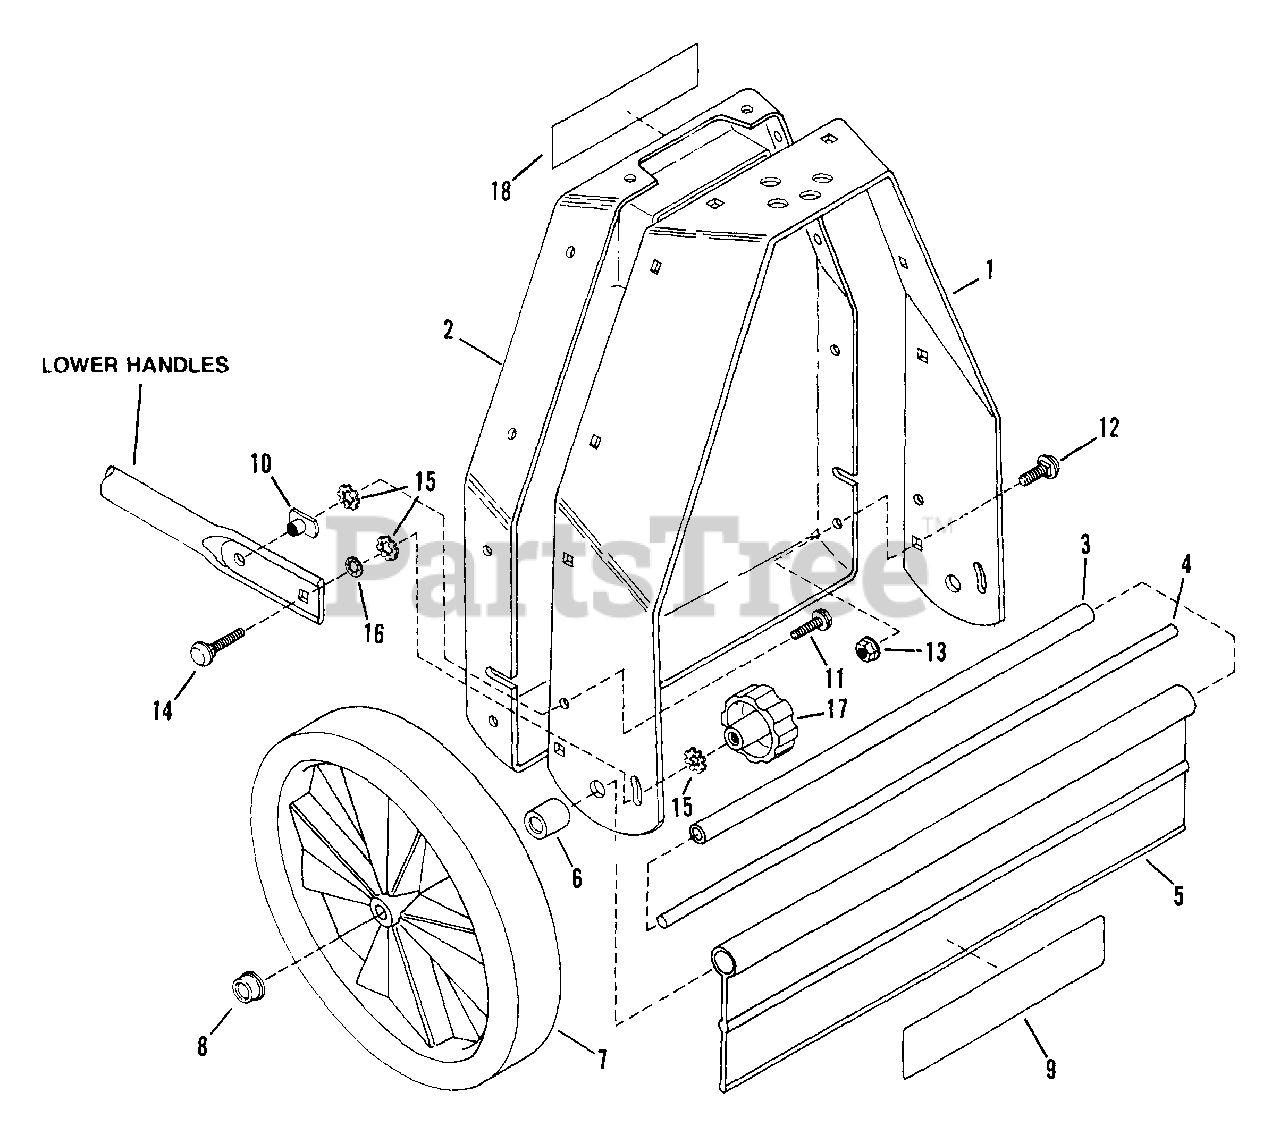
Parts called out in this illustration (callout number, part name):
1	FRAME, Main
2	PANEL, Main Frame
3	SPACER, Tube Frame
4	SHAFT, Axle
5	SHIELD, Trailing
6	BUSHING, Axle
8	NUT, 3/8 Push
9	LABEL, Trailing Shield
10	T-NUT, 5/16-18
11	BOLT, 5/16-18 x 1/2" Hex Flange Lock
12	BOLT, 1/4-20 x 1/2" Short Neck Carriage
13	NUT, 1/4-20 Hex Flange Lock
14	BOLT, 5/16-18 x 3/4" Short Neck Carriage
15	WASHER, 5/16 Int./Ext. Tooth Lock
16	RETAINER, 5/16 Bolt
17	KNOB, 5/16-18 Plastic
18	LABEL, Adjustment
